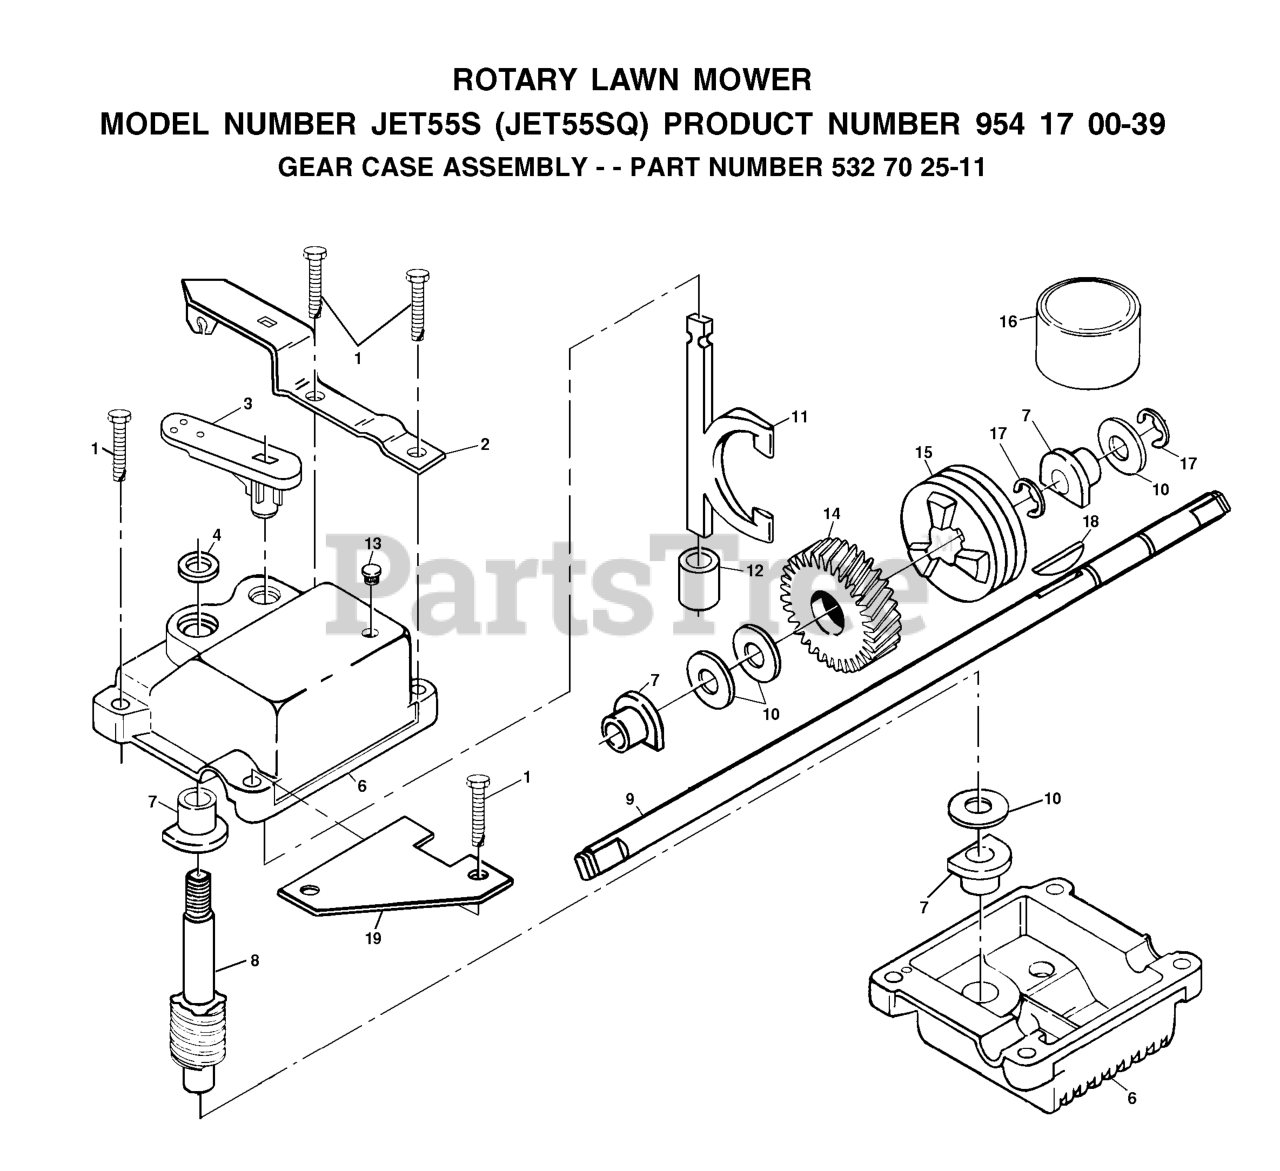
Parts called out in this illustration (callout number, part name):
1	SCREW
2	BRACKET
8	WORM SHAFT
9	DRIVE SHAFT, 20-5/8"
10	THRUST WASHER
11	YOKE.VIBRATORY FINISH.
13	PLUG.AUGER.GEAR.BOX.SNOW
14	GEAR.HELICAL
15	CLUTCH JAW
16	GREASE
18	HI PRO KEY
19	BRACKET SPRING
